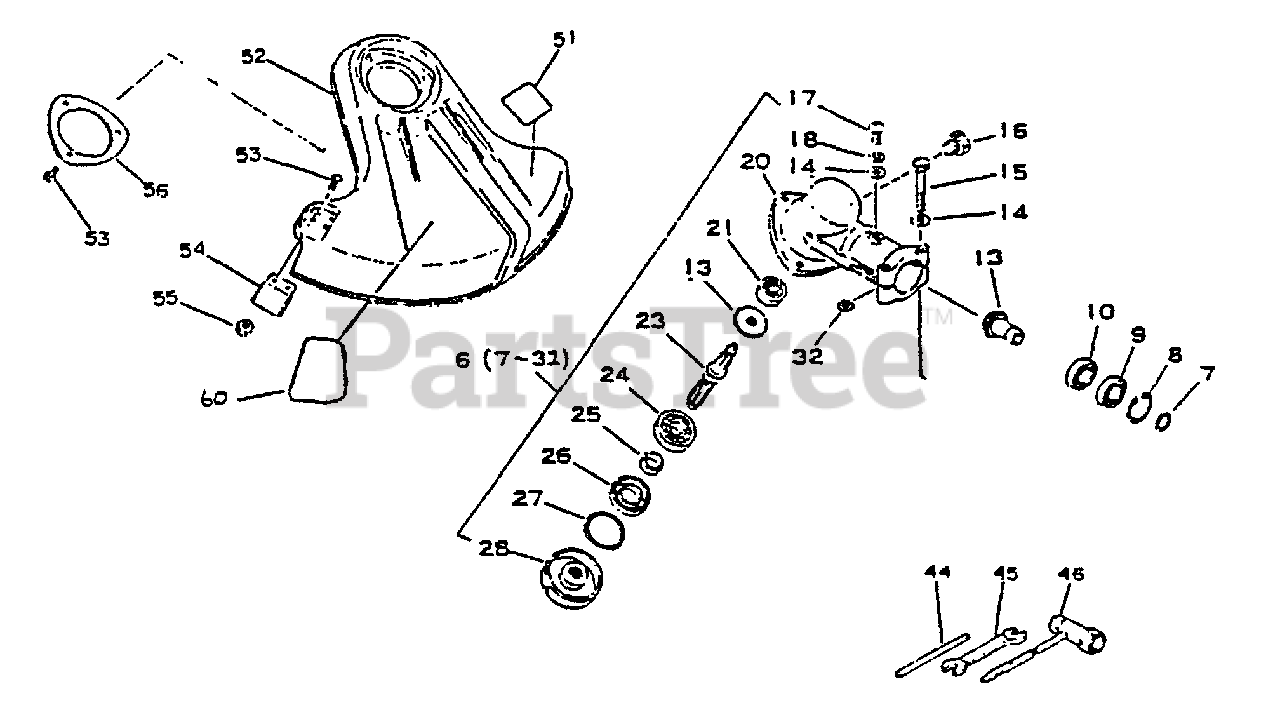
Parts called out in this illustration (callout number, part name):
6	GEAR CASE ASSY
7	RING, SNAP Ø12
8	RING, SNAP Ø22
9	BEARING, BALL 6900Z
10	BEARING, BALL 6900
13	GEAR SET
14	WASHER, FLAT 5.5×10×0.8
15	BOLT 5×35 SP
16	BOLT 8×8 SP
17	SCREW 5×10
18	WASHER, SPRING 5
20	HOUSING, GEAR CASE
21	BEARING, BALL 609
23	SHAFT, GEAR
24	BEARING, BALL - 6201 C3
25	SPACER 11.8×15×9
26	SEAL, OIL 22
27	RING, SNAP Ø32
28	PLATE, ADAPTER - UPPER
44	TOOL, LOCKING 5×120 MM
45	SPANNER 8×10
46	T-WRENCH 17x-19 L200
51	LABEL - ECHO
52	SHIELD ASSY
53	SCREW 5×16
54	CUTTER, LINE
55	NUT M5
56	PLATE, SHIELD Ø49.5 MM
60	LABEL, CAUTION
